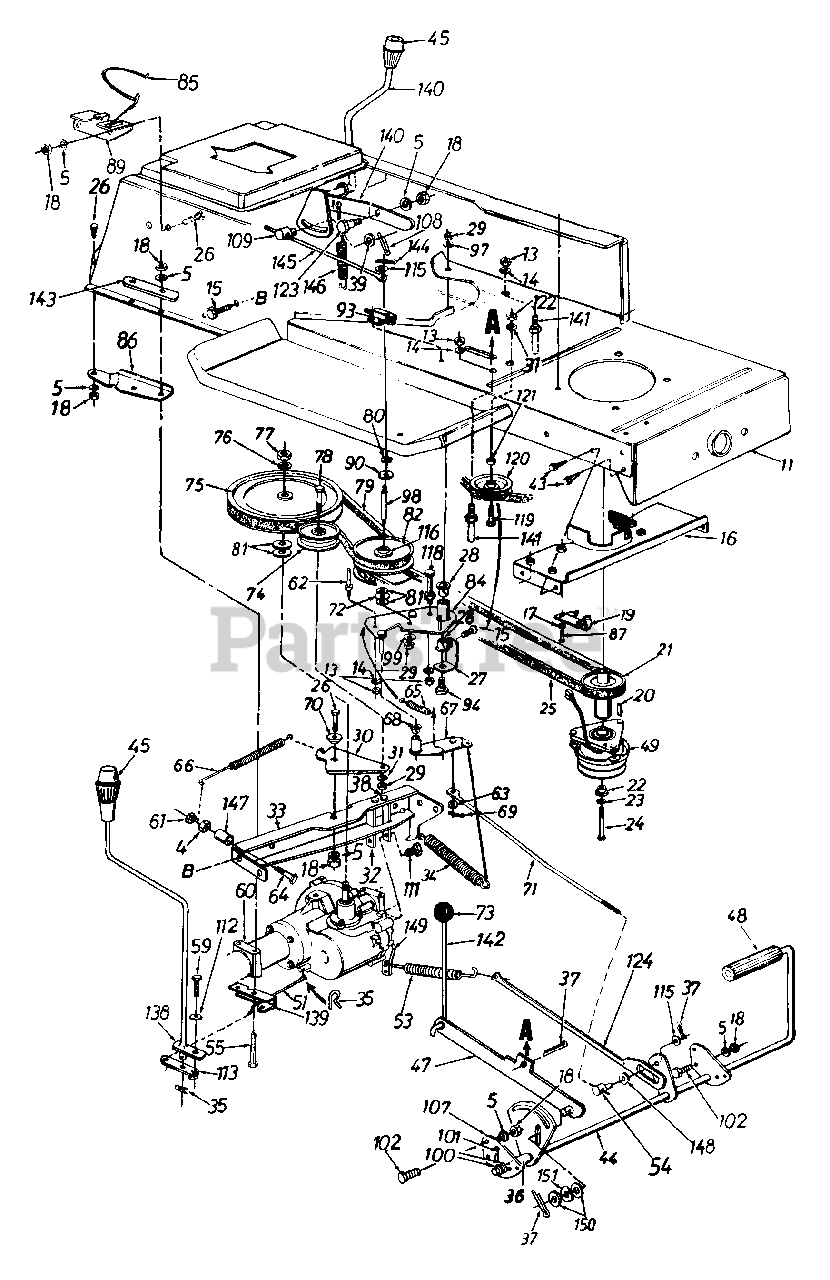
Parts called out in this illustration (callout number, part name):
4	Hex Nut 5/16-24 Thd.
5	L-Wash. 5/16" I.D.
14	L-Wash. 1/4" I.D.
15	Hex Wash. TT-Tap Scr. 5/16-18 x .62" Lg.
18	Hex Nut 5/16-18 Thd.
21	Engine Pulley
22	Shld. Spacer .445" I.D.
23	L-Wash. 7/16" I.D.
24	Hex Bolt 7/16-20 x 3.25" Lg.
25	Variable-Speed Belt
26	Hex Bolt 5/16-18 x .75" Lg.
27	Bearing Shaft Bracket Ass'y.
28	Flanged Nyliner Brg. .63" I.D. x .6" Lg.
29	Hex Nut 3/8-24 Thd.
30	Idler Bracket
31	L-Wash. 3/8" I.D.
35	Inter. Cotter Pin
36	Spacer .63" I.D.
37	Cotter Pin 1/8" Dia. x 1.0" Lg.
38	Self-Tap Scr. 5/16-18 x .5" Lg.
39	FL-Wash. .51" I.D. x .75"
43	Hex Wash. Hd. S-Tap Scr. 1/4-20 x .50" Lg.
44	Clutch/Brake Pedal Ass'y.
47	Parking Brake Lockout Brkt. Ass'y.
48	Foot Pad
49	Electric Clutch
51	Shift Lever Rod
53	Ext. Spring 3.6"
54	Ferrule
55	Hex Bolt 5/16-18 x 3.25"
59	Hex Bolt 1/4-28 x .62" Lg.
60	Transaxle Complete
61	Hex L-Nut 1/4-20 Thd.
62	Belt Guard Pin 1/4-20 Thd.
63	Fl-Wash. .34" I.D. x .68" O.D.
64	Hex Wash. TT-Tap Scr. 1/4-20 x 1.75"
65	Ext. Spring 2.59" Lg.
66	Ext. Spring .5" O.D. x 4.35"
68	Flanged Bearing
69	Cotter Pin 3/32" Dia.
70	Shoulder Spacer .27" Lg.
71	Speed Control Link
72	Truss Bearing .56 Dia. x 1.25"
74	Fl-Idler Pulley 3.25" x .75"
76	L-Wash. 1/2" I.D.
77	Hex Jam Nut 1/2-20 Thd.
78	Hex Bolt 3/8-24 x 1.75" Lg.
79	Variable Speed Belt
80	Snap Ring .56" Dia.
81	Fl-Wash. .56" I.D. x 1.0" O.D.
82	Variable Speed Pulley Ass'y. 5" O.D.
89	Speed Cont. Rod Brkt.
90	Teflon Washer .565" I.D.
93	Safety Switch (Clutch)
94	Shld. Bolt 3/8-24 x 3.12" Lg.
97	Bell-Wash. .38" I.D. x .88"
99	Bell-Wash. .39" I.D. x 1.12"
100	Fl-Wash. .64" I.D. x .94"
101	Cotter Pin 1/8" Dia. x 1.25" Lg.
102	Hex Wash. Hd. Scr. 5/16-18 x .62" Lg.
109	Ferrule
111	Hex Wash. Tap Scr.
112	Bell-Wash. .265" I.D. x .75"
113	Shift Lever Link Ass'y.
115	Fl-Wash. .385" I.D. x .62"
116	Needle Brgs.
118	Hex Bolt 1/4-20 x 3.5" Lg.
119	Hex Bolt 3/8-16 x 1.25" Lg.
120	Fl-Idler w/Flanges 2.75" O.D.
121	Fl-Wash. .39" I.D. x 1.12" O.D.
122	Hex Nut 3/8-16 Thd.
123	Shld. Bolt .437" Dia. x .162"
124	Brake Rod Ass'y.
138	Shift Lever Ass'y.
139	Shift Lever Support Brkt.
140	Speed Selector Lever Ass'y.
141	Belt Guard Pin
142	Brake Lockout Rod
144	Cotter Pin 1/8" x 3/4" Lg.
145	Speed Selector Rod
146	Ext. Spring 3.97" Lg.
147	Spacer .326" I.D. x .47"
148	Fl-Wash. 5/8" I.D. x 1.25"
149	Actuating Arm
150	Fl-Wash. .385" I.D. x .87" O.D.
151	Wave Wash. .38" I.D. x .75"
